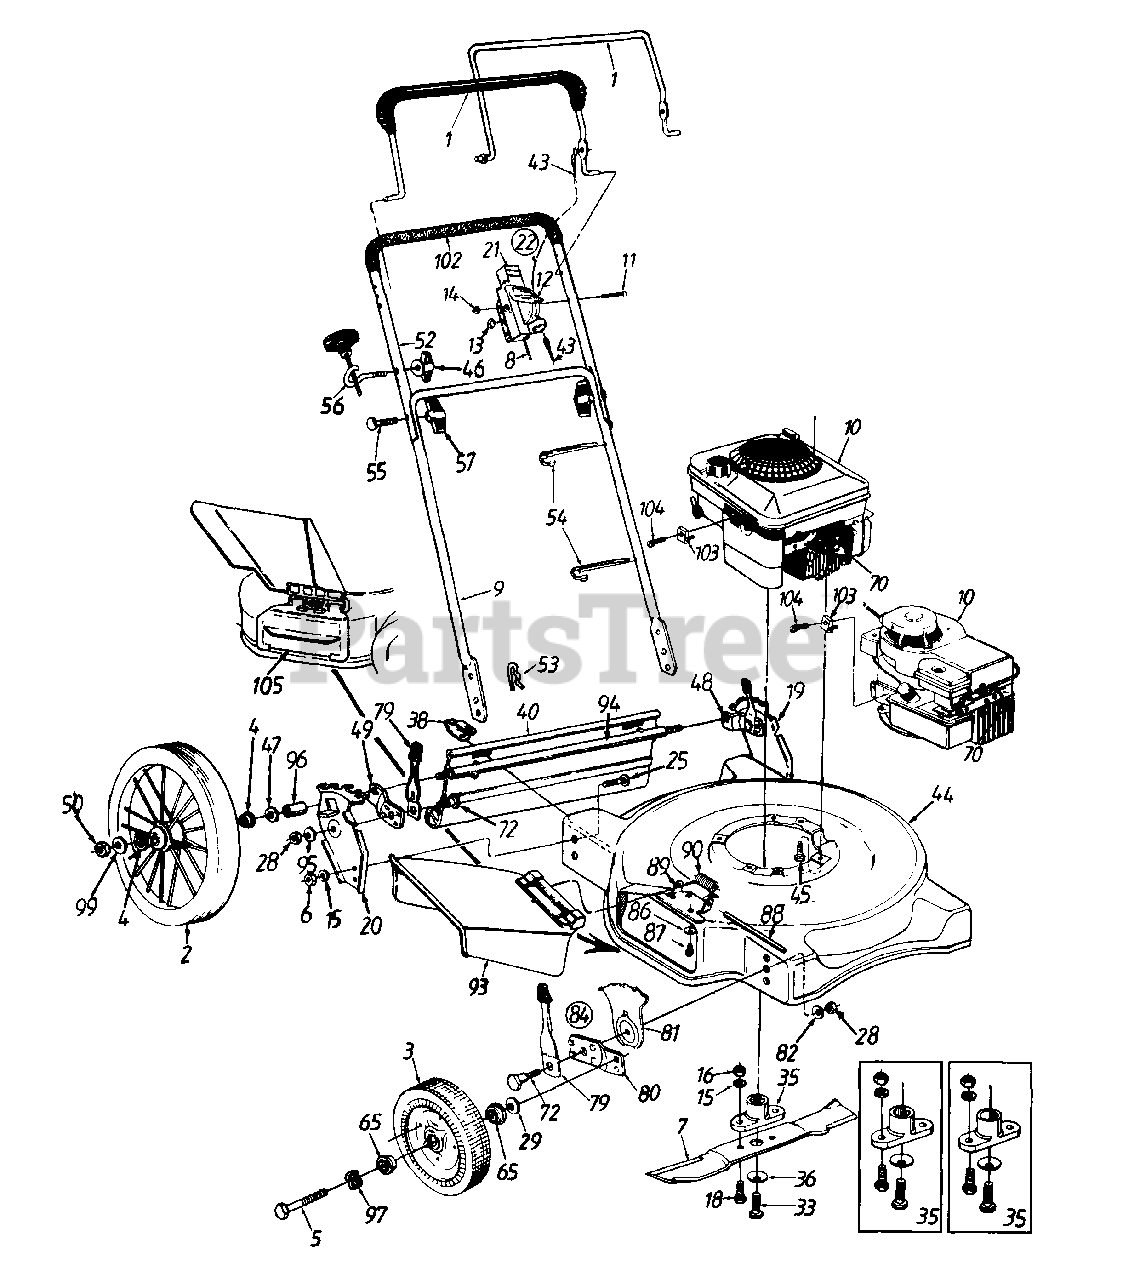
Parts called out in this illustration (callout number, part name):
2	16" Wheel Ass'y.
3	Front Wheel Ass'y. w/ Plastic Brgs.
4	Bearing 1/2" I.D.
5	Front Axle Bolt
6	Hex Nut 3/8-24 Thd. (Gr. 8)
7	22" Blade
8	Throttle Control Wire - 51"
10	Engine
11	Oval C-Sunk Mach. Scr.
12	Throttle Lever
13	Spr. Wash. .66" I.D.
14	Hex L-Nut 1/4-20 Thd.
15	L-Wash. 3/8" I.D.
16	Hex Nut 3/8-24 Thd.
18	Hex Bolt 3/8-24 x 1.0" Lg.
22	Throttle Box Comp.
25	Ribbed Neck Bolt 3/8-24 x .80"
28	Hex Nut 3/8-16 Thd.
29	Bell-Wash. .400" I.D. x .88"
33	Hex Bolt 3/8-24 x 1.5" Lg.
35	Blade Adapter Kit
36	Bell-Wash. .39" I.D.
38	Hinge Clip
40	Rear Flap Ass'y.
43	Control Cable - 39"
46	Handle Knob 1/4-20 Thd.
47	Wave Wash. .51" I.D.
48	Small Pivot Bar - L.H.
49	Small Pivot Bar - R.H.
50	Hex Jam Nut 3/8-16 Thd.
54	Cable Tie
55	Curved Hd. Bolt 5/16-18 x 2" Lg.
56	Rope Guide
57	Hand Knob
65	Bearing
70	Spark Plug Boot
72	Shoulder Bolt .50" Dia.
79	Spring Lever Ass'y. w/Knob
81	Height Adj. Plate
82	Bell-Wash. .39" I.D. x 1.38"
84	Front Height Adj. Ass'y. Comp. - R.H.
86	Bell-Wash. .285" I.D. x .75"
87	Hex Wash. Hd. Tap Scr. 1/4-20 x .5" Lg.
88	Hinge Pin
89	Adapter Plate
90	Torsion Spring
93	Chute Deflector Ass'y. Comp.
94	Rear Axle
95	Bell-Wash. .39" I.D. x 1.13"
96	Spacer .55" I.D. x .75"
97	Wave Washer .51" I.D. (Used w/Ball Brg. Wheels)
99	Fl-Wash. .406" I.D. x .81"
102	Foam Grip
103	Casing Clamp
104	Hex Wash. Hd. Tap Scr. #10-32 x .62" Lg.
105	Mulching Baffle
